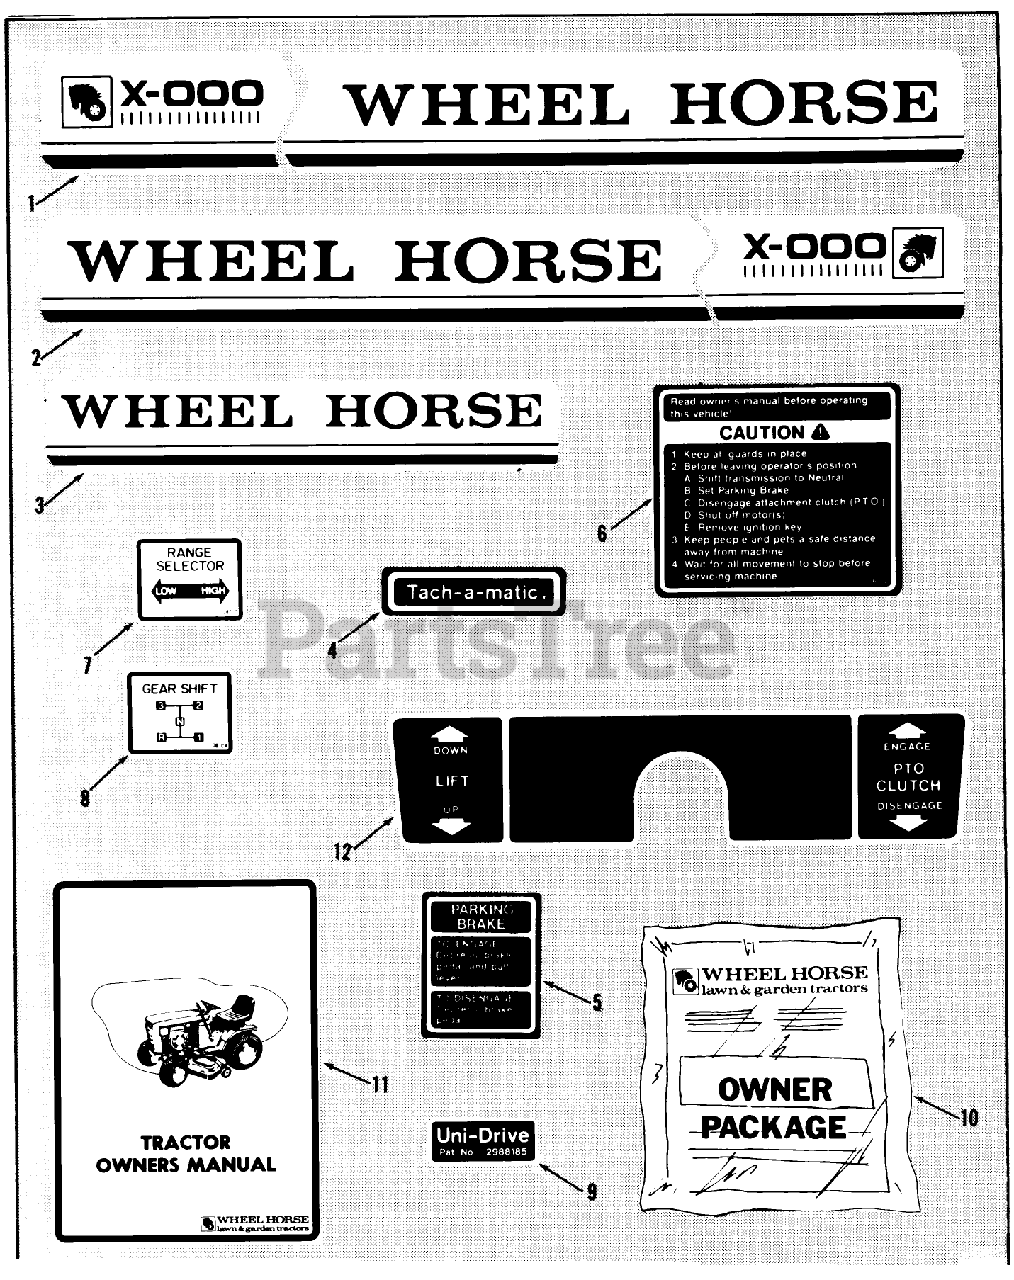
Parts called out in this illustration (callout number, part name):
1	Decal LH GT-2500
2	Decal RH GT-2500
5	DECAL-PARKING BRAKE
7	DECAL, RANGE SELECTOR
10	Loose Parts Package
11	Tractor Owner-s Manual
12	Decal-Control Housing
